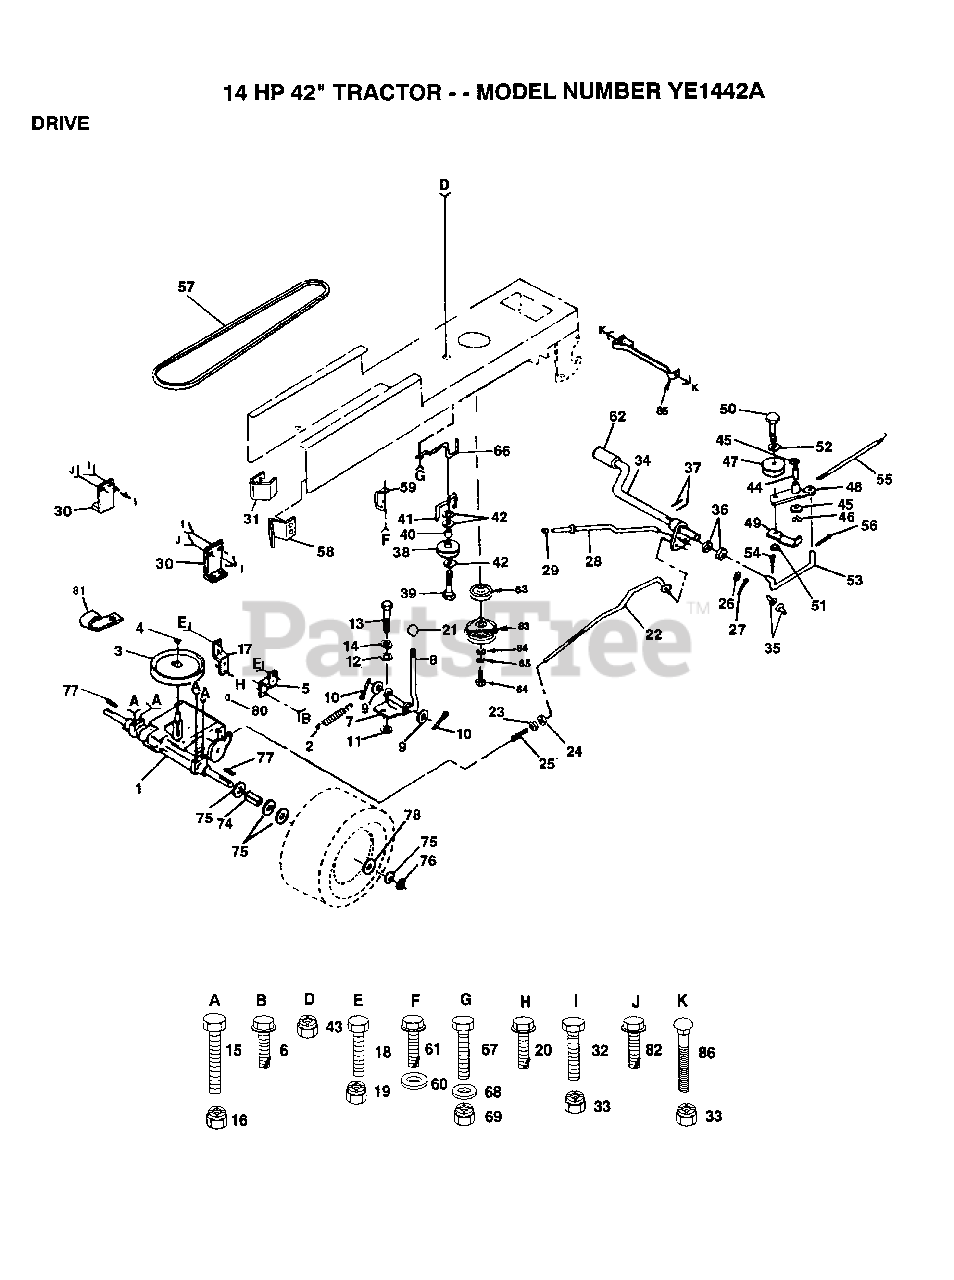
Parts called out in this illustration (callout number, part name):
3	PULLEY TRANS
5	STRAP TORQUE
6	SCREW
8	SHIFT ROD
9	WASHER
10	PIN COTTER 1/8
11	WASH-SHFT PLT LT
12	WASHER LT
14	LOCKWASHER
15	BOLT
17	STRAP TORQUE
20	SCREW
21	KNOB.DUCKHEAD.1/2
22	BRAKE ROD
23	NUT
24	NUT
25	SPRING ROD LT
26	WASHER
27	COTTER PIN
28	BRAKE PARK ROD
29	PLUNGER CAP T
30	TRANSAXLE MTG BKT
31	"KEEPER,BELT LH T"
32	BOLT
35	NYLON BEARING
36	WASHER LT
38	PULLEY.IDLER.FLAT
39	BOLT
40	SPACER T
41	BELT KEEPER LT
42	WASHER
44	"LY, BEARING"
45	WASHER LT
46	KLIP RING
48	ARM IDLER
49	RETAIN BELT
52	WASHER
53	"LINK, CLUTCH T"
54	COTTER PIN
55	"SPRING, RETURN LT"
56	COTTER PIN
58	"KEEPER,BELT RH T"
60	WASHER
61	SCREW
62	PEDAL COVER T
64	"BOLT,HEX"
65	LOCKWASHER
66	KEEPER.BELT.ENG.L
67	BOLT
68	WASHER
74	SPACER LT
75	WASHER
76	E-RING LT
77	SQUARE KEY
78	WASHER
81	CLIP T
82	SCREW
84	WASHER
